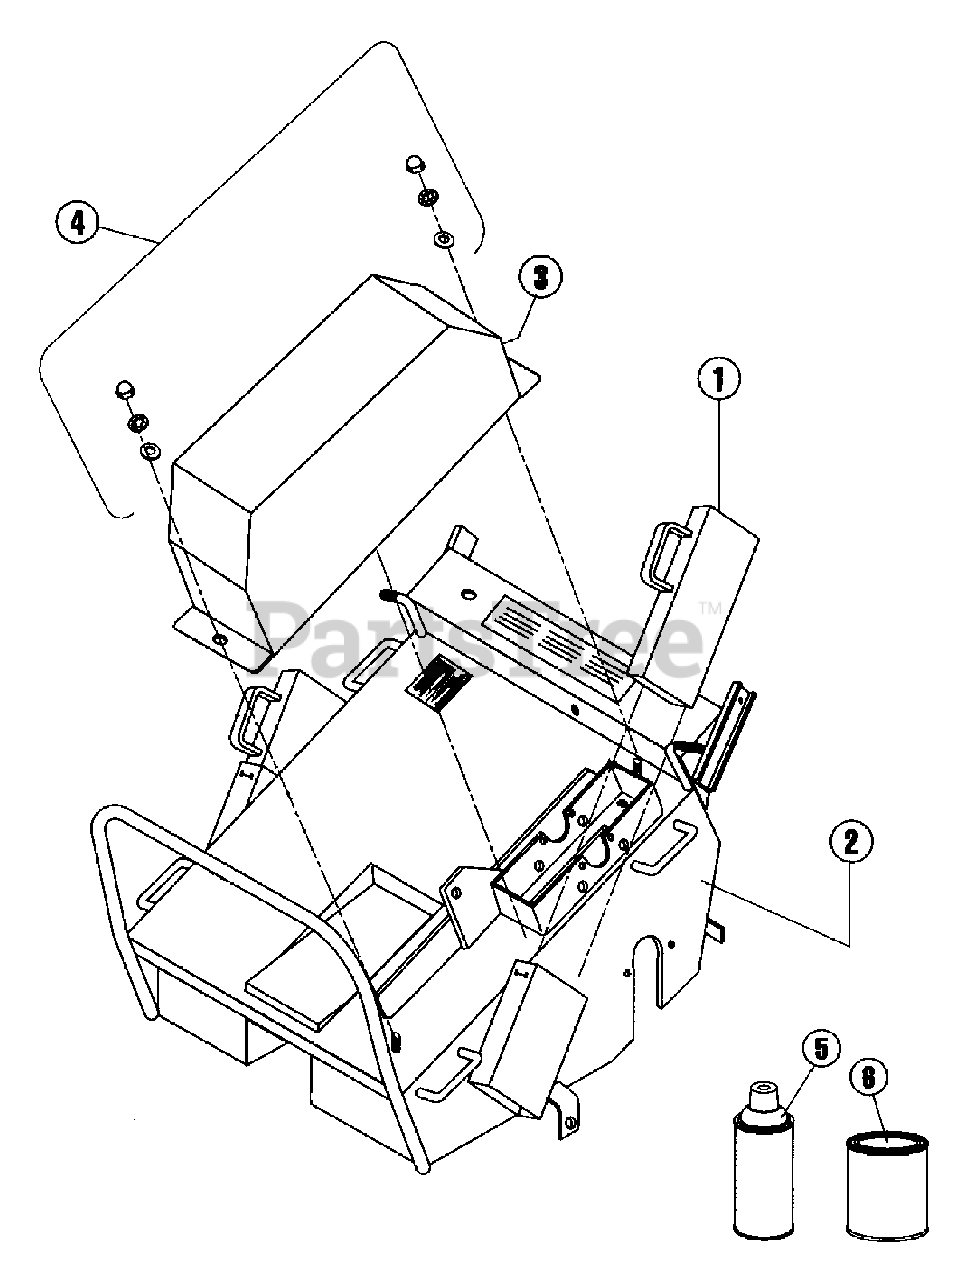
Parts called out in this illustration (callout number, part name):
1	Weight, 36 lbs., solid steel
2	Housing with decals
3	Drive guard with decals
4	Drive guard fastener kit
5	Paint, orange, 12.5 oz. can
6	Paint, orange, 1qt. can
7	Decal kit, AR19
